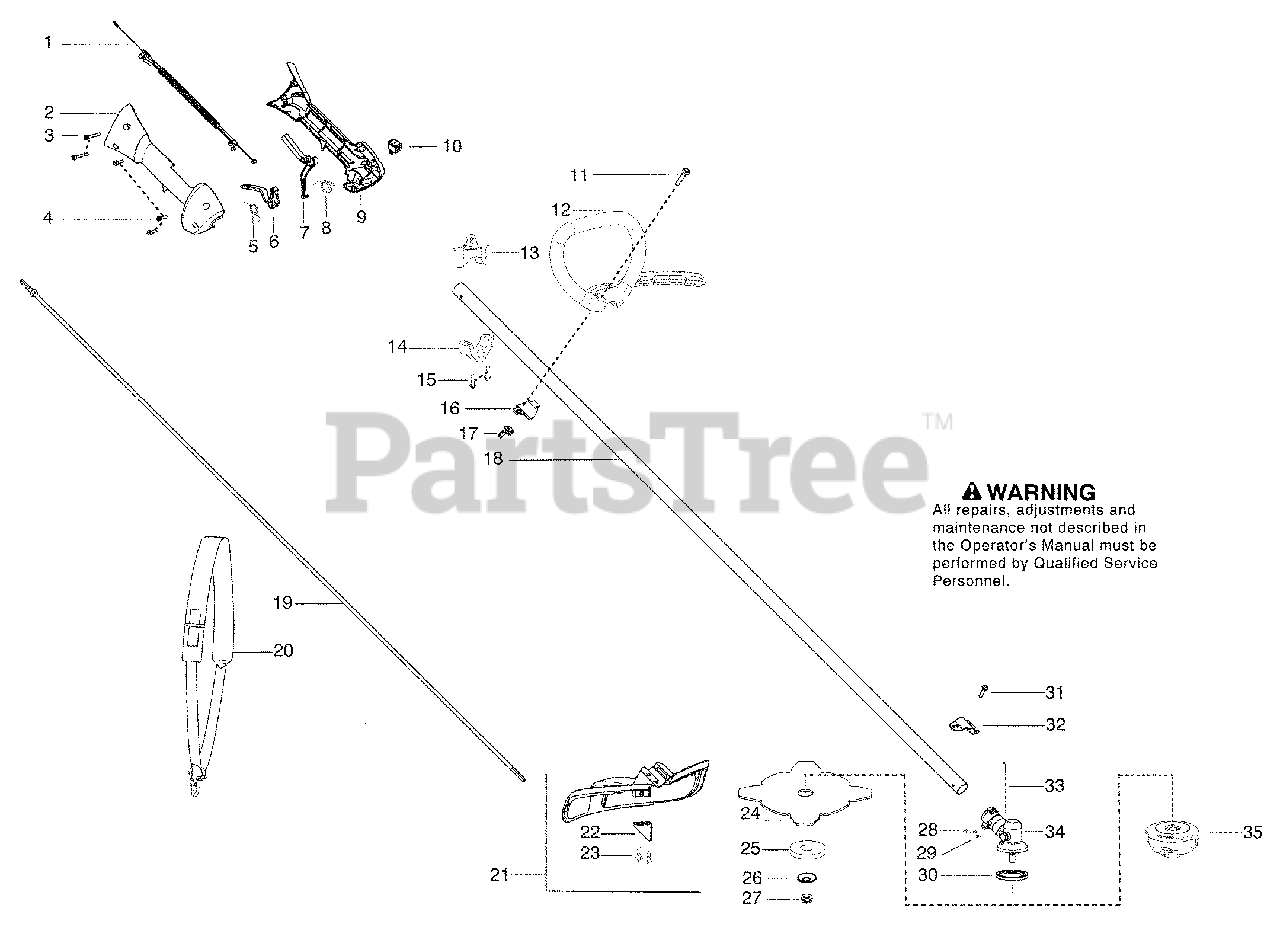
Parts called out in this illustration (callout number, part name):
1	Assy-Cable/Wire Harness
2	Housing-Throttle - RH
5	Spring-Trigger
7	Lockout-Throttle
8	Spring-Lockout
9	Housing-Thottle - LH
10	Kit-Switch
12	Assy-Handle/J-Bar
13	Clamp-Harness
14	Clamp-Harness
16	Clamp - Handle
17	Wingnut
18	Kit-Driveshaft
20	Harness-w/o warning
21	Kit-Shield
22	Limiter - Line
24	Blade - Grass
25	Cup - Support
26	Support - Flange
27	Locknut - Blade
30	Driver Disc
32	Bracket - Shield
33	Pin - Locking
34	Assy - Gearbox
35	Assy-T25 Cutting Head
